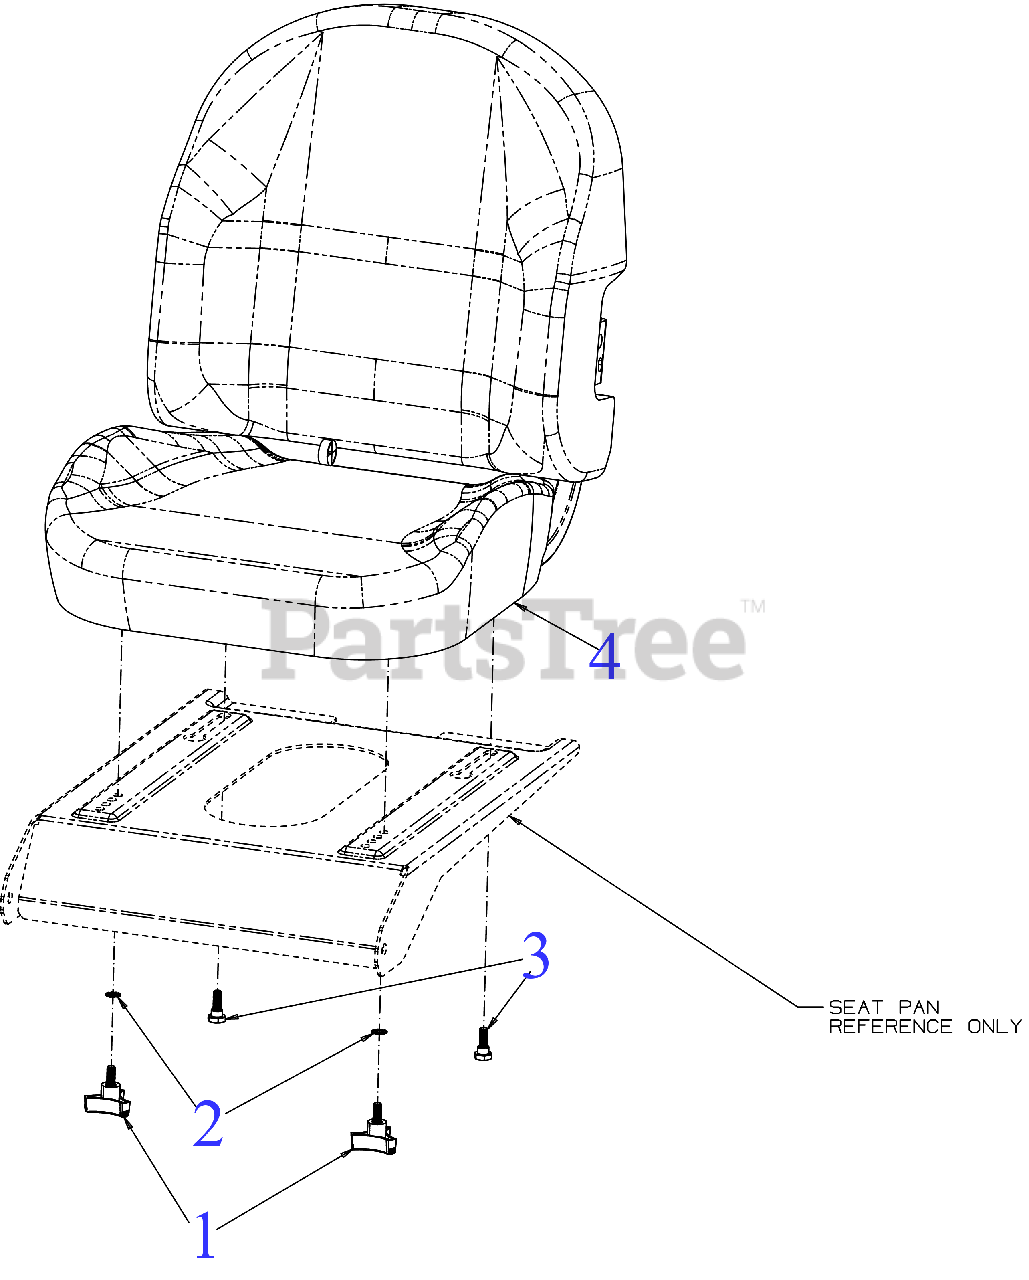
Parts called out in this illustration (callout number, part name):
1	3 PRONG KNOB 5/16-18
3	SHOULDER SCREW .437
4	SEAT (CUB)
